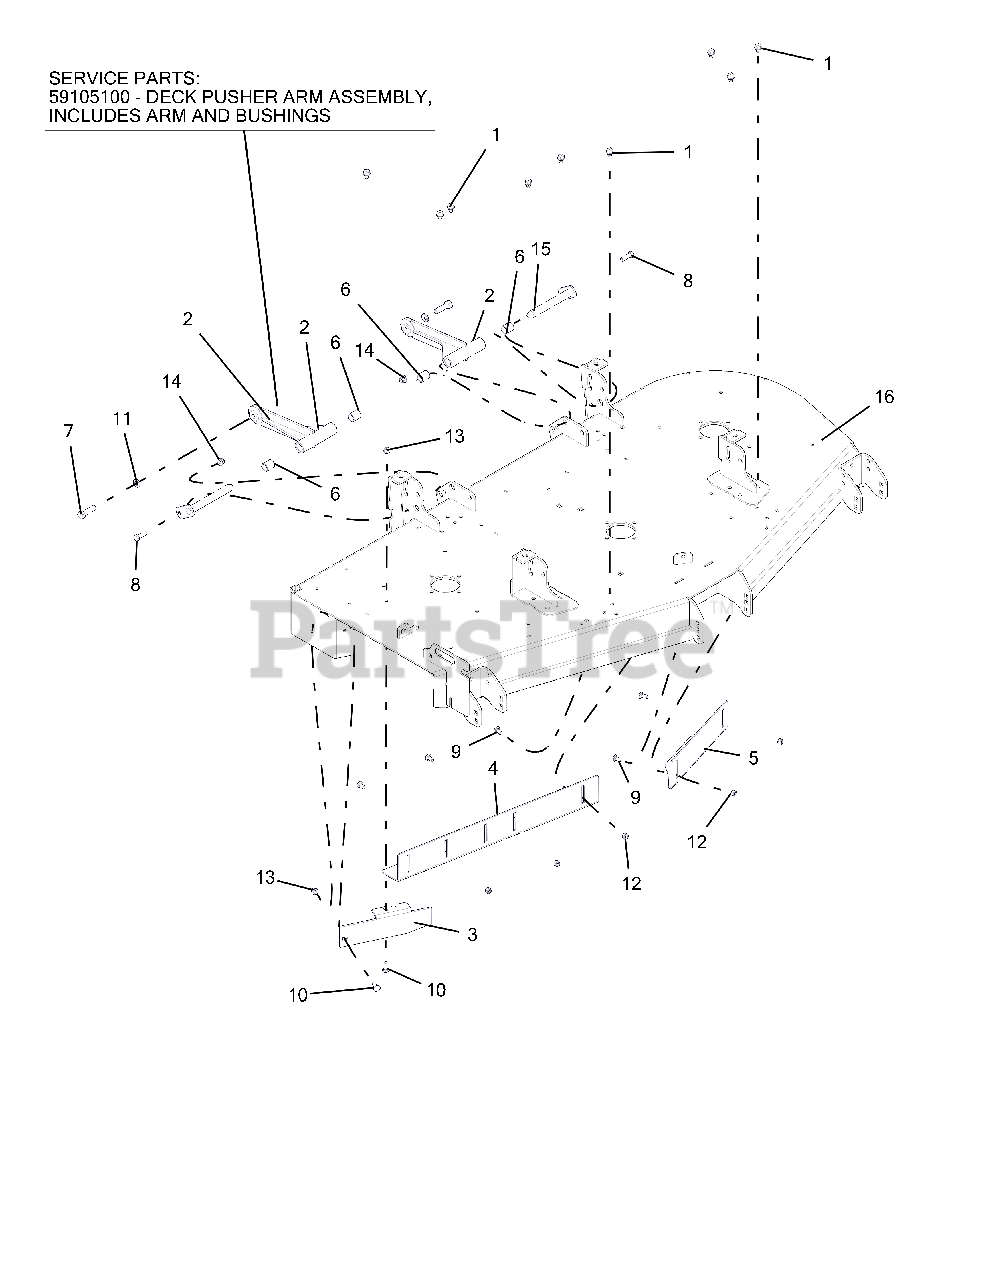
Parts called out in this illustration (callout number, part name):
1	SCR-TAP .38-16X.50 HWH TR YWZ
2	WLDMT, DECK PUSHER ARM
2	DECK PUSHER ARM ASSEMBLY
3	BAFFLE, 60" DISCHARGE
4	BAFFLE, 60" RH VACUUM
5	BAFFLE, 60" LH VACUUM
6	BRG, .750 X .875 X 1.000
7	BLT-HEX .50-13X1.75 GR5 YWZC EP80
8	BLT-HEX .38-16X1.25 GR5 YWZC
9	BLT-RDHDSQNK .31-18X.75 G5 YWZC
10	BLT-RDHDSQSHNK .31-18X1.00 G5 Y
11	WSHR-LK .50X.125 REG YWZC
12	NUT-LK-NYL .312-18 YWZC
13	NUT-LK-NYL-FLG .31-18 YWZC
14	NUT-LK-NYL-FLG .38-16 YWZC
15	WLDMT, MOWER MTG. PIN
16	KIT, PT160 MOWER DECK W/SAFETY DECALS-RED
